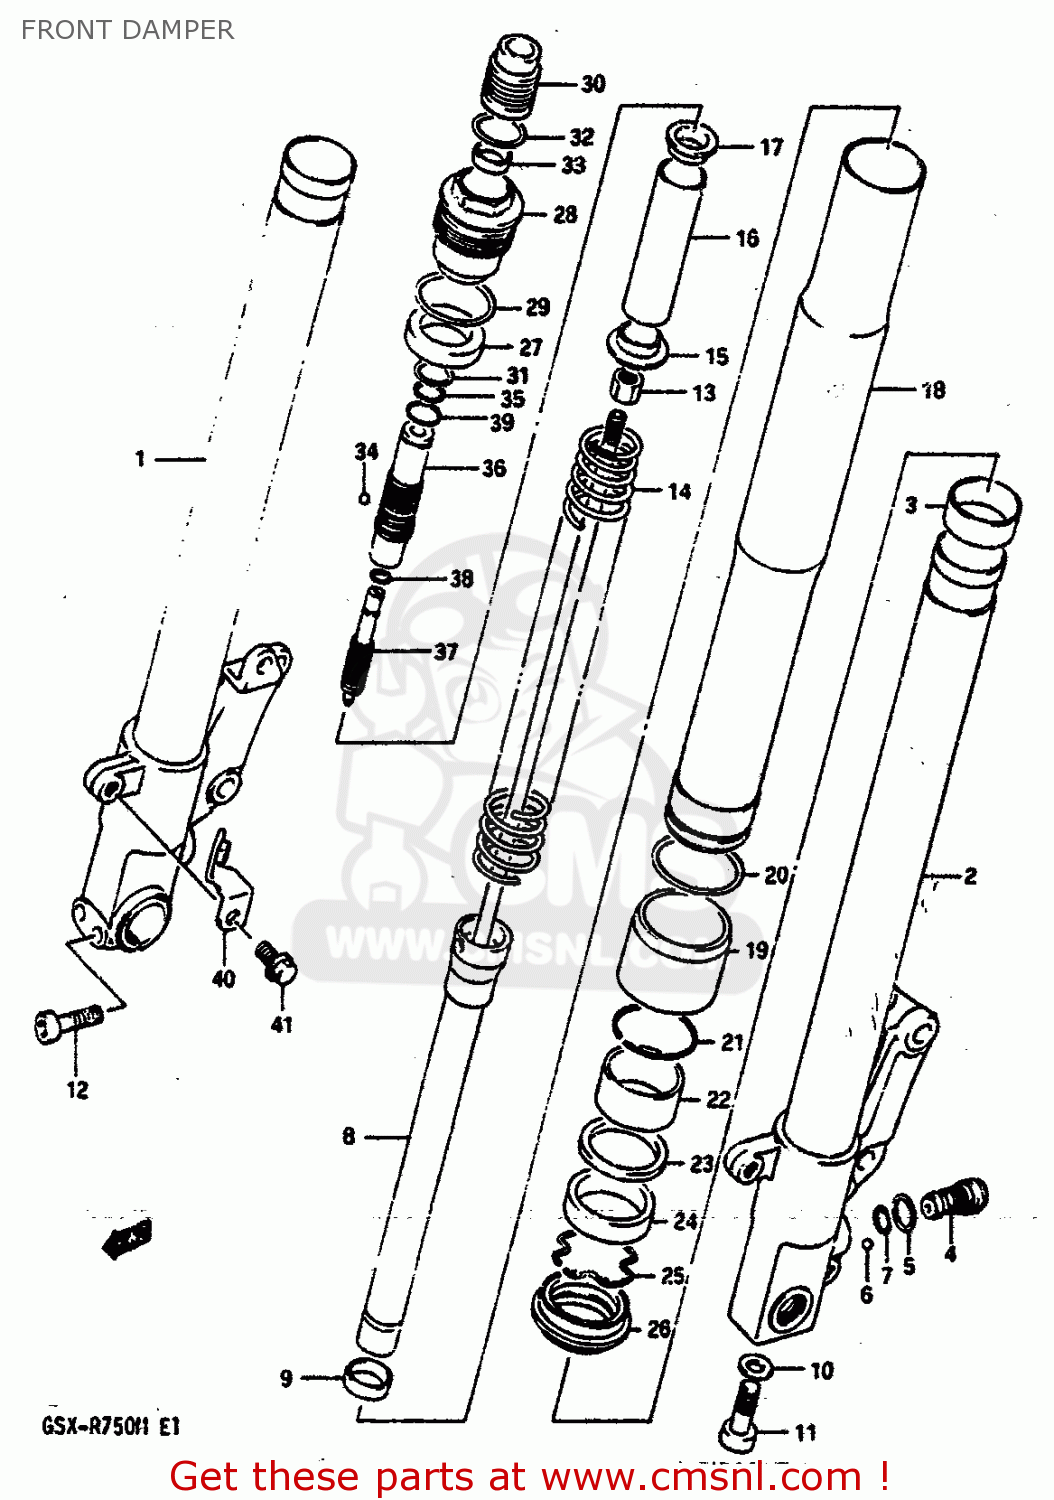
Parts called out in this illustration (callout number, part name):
1	TUBE,INNER,R
2	TUBE,INNER,L
3	BUSH,SLIDE
4	PIECE,ADJUSTER
5	O RING
6	BALL
7	EXPANDER
8	DAMPER,FRONT
9	PLATE,CENTERING
10	WASHER(10X15X1.5)
11	BOLT
12	BOLT ,8X50
13	NUT
14	SPRING,MAIN
15	GUIDE,SPRING
16	SPACER,SPRING
17	JOINT,SPRING
18	TUBE,OUTER
19	CASE,OIL SEAL
20	O RING
21	RING,SNAP
22	BUSH,GUIDE
23	SPACER,SEAL
24	SEAL,OIL
25	CIRCLIP,FORK OIL SEAL
26	DUST SEAL,FRONT FORK
27	RUBBER,SEAT
28	BOLT,FORK
29	O RING,FORK BOLT
30	ADJUSTER,SPRING
31	O RING
32	O RING
33	PLATE, SPRING ADJUSTER
34	BALL
35	EXPANDER
36	CASE,ADJUSTER
37	PIECE,ADJUSTER UPR
38	O RING
39	RING,STOPPER
40	PLATE,FRONT FENDER,LEFT
41	BOLT 8X12
